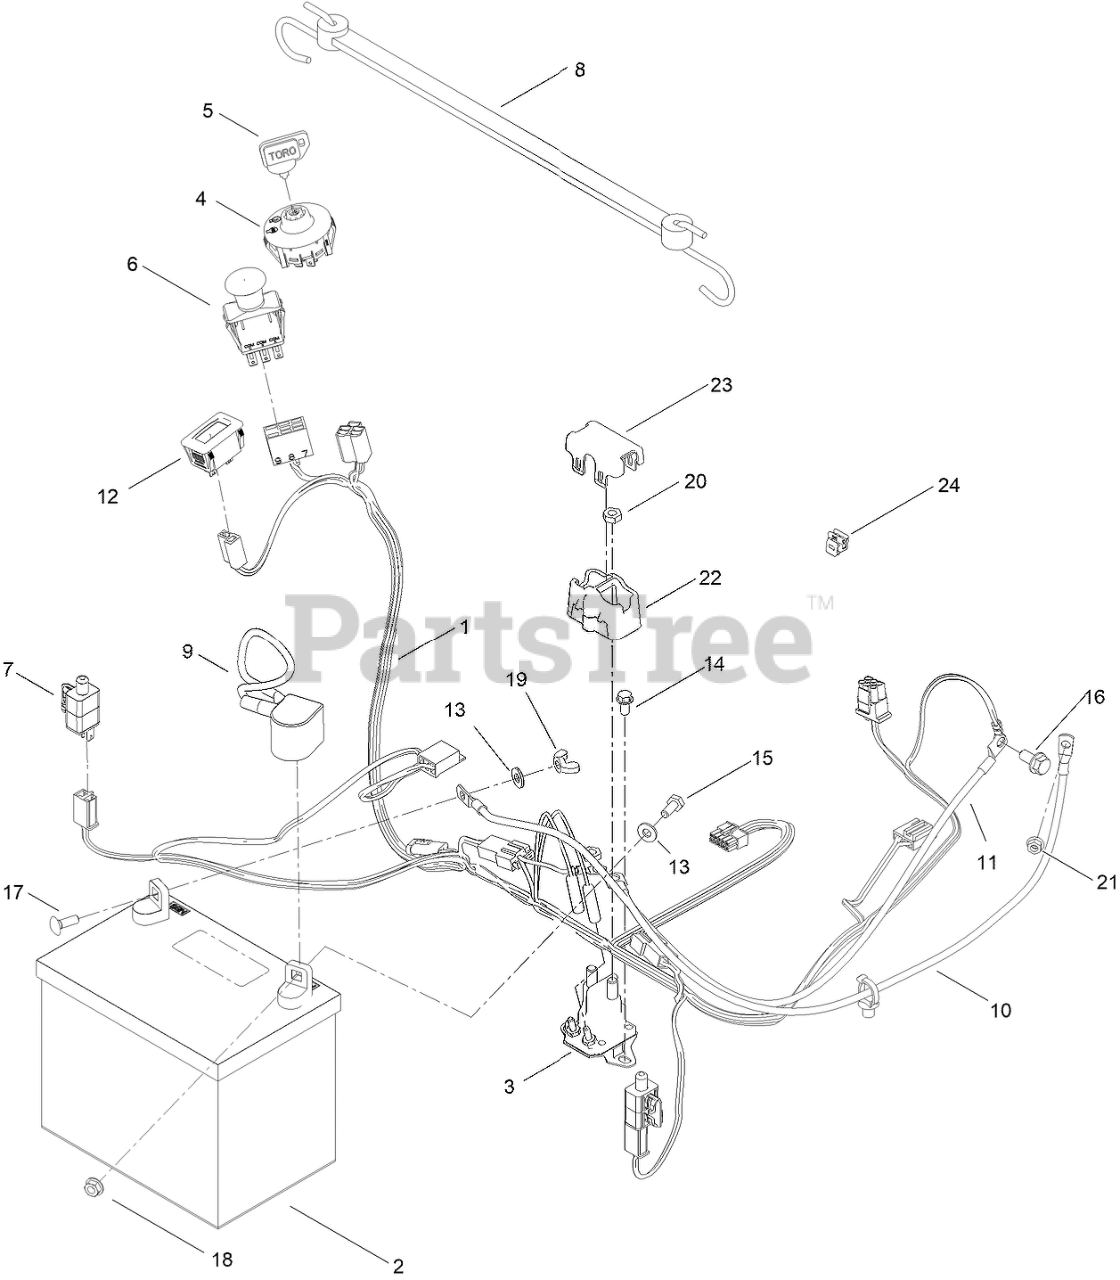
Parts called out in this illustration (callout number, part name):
1	HARNESS-WIRE
2	BATTERY
3	SOLENOID
4	SWITCH-IGNITION
5	KEY-IGNITION
6	SWITCH-PTO
7	SWITCH
8	STRAP-RUBBER
9	CABLE-BATTERY, POS
10	CABLE-BATTERY, RED (8 GAUGE)
11	CABLE-BATTERY, BLACK
12	HOURMETER
13	WASHER-FLAT
14	SCREW-HWH
15	SCREW-HH
16	SCREW-HHF
17	BOLT-CARR
18	NUT-HF
19	NUT-WING
20	NUT-JAM
21	NUT-HF
22	COVER-SOLENOID
23	CAP-SOLENOID
24	CLIP-HARNESS
